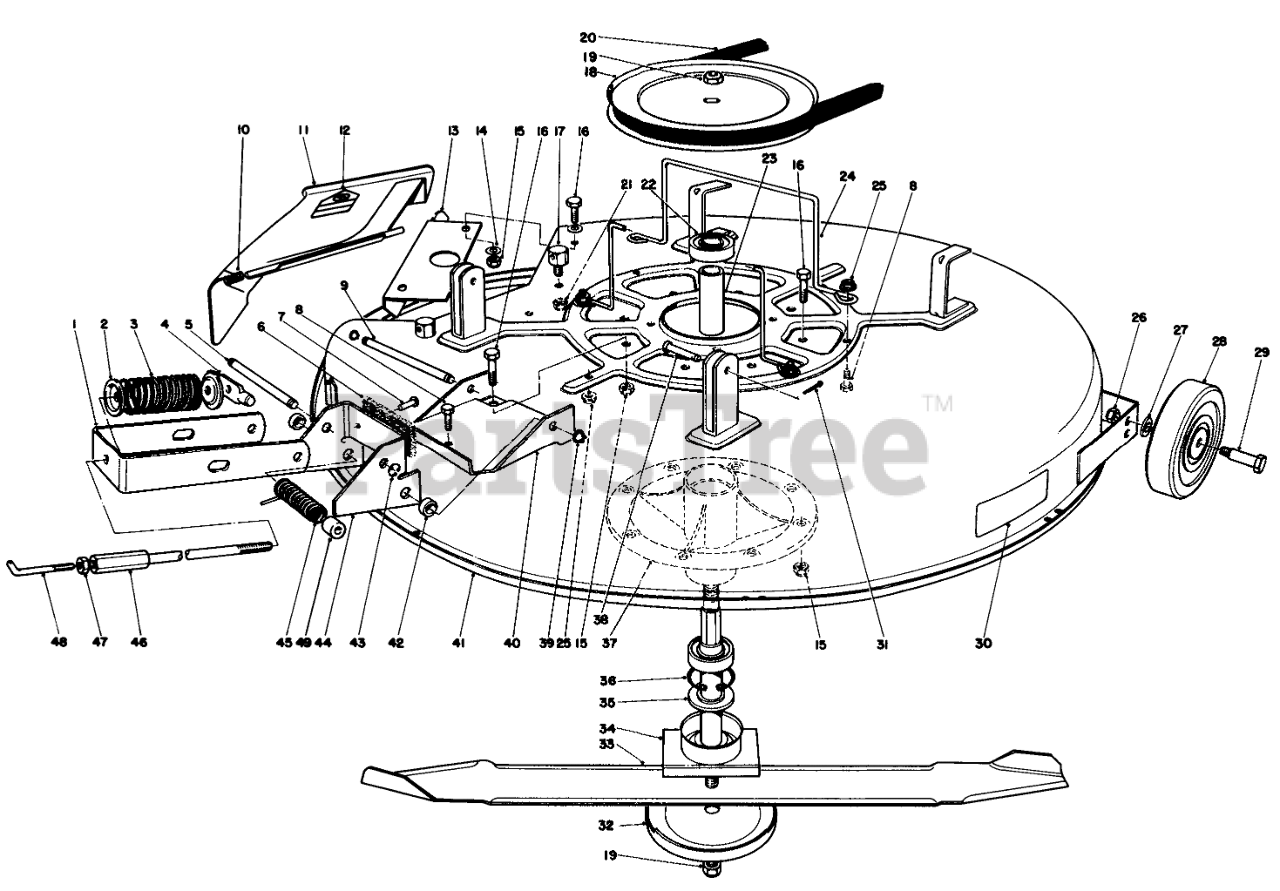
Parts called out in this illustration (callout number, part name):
1	Bracket-Engagement
2	RETAINER-SPR. TOP
3	SPRING-COMPRESSION
4	SHAFT-DECK ADJ.
5	Pin-Clevis
6	BRAKE PAD
7	RIVET .187 X 7/16 BRASS
8	SCREW-HH
9	CLEVIS PIN
10	SPRING
11	Deflector Assembly (Incl. Ref. #12)
12	DECAL-DANGER
13	Baffle Deck
14	WASHER-PLAIN
15	NUT-LOCK, NI
16	SCREW-HH
17	POST-PIVOT
18	PULLEY
20	V-BELT, DECK
21	NUT-LOCK, SIDE
22	BEARING-BALL
23	Spacer-Bearing
24	GUIDE-BELT
25	NUT-LOCK, HHF
26	NUT-LOCK, NI
27	WASHER-FLAT
28	WHEEL-DECK
29	BOLT-WHEEL
30	DECK DECAL
31	PIN-COTTER
32	Cup
33	Blade
34	SPINDLE SHAFT WA
35	SPACER-SPINDLE
36	RING-RETAINING
37	SPINDLE
38	PIN-CLEVIS
39	RING-RETAINING
40	DECK ENGAGE CHANNEL R
41	Cutter Deck
42	DECK BRAKE SPACER
43	E-RING
44	Support Deck Brake Assembly (Incl. Ref. #6 & 7)
45	SPRING
46	ADJ HUB WA
47	NUT-JAM
48	ADJ. ROD
49	CHAIN TENSION ROLLER
